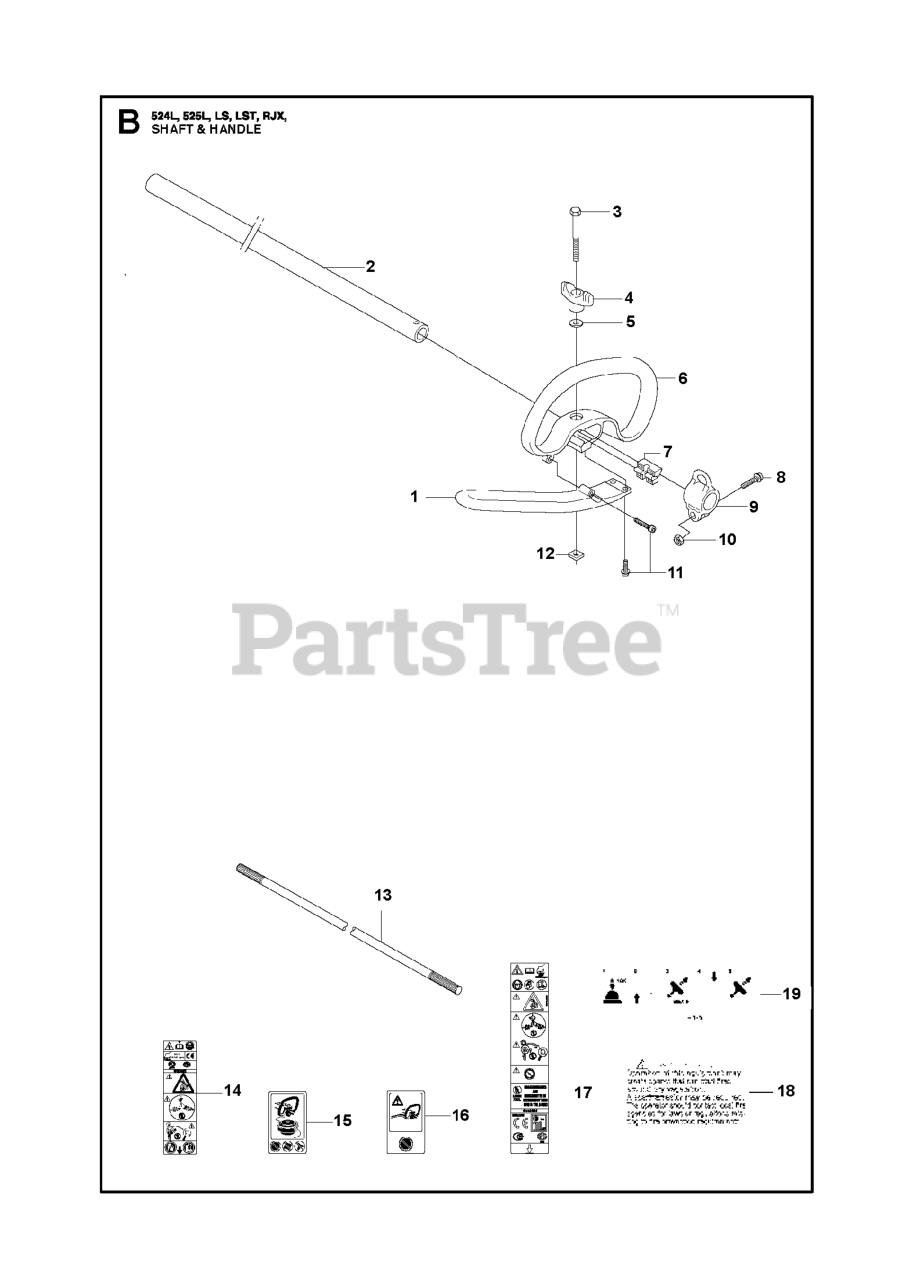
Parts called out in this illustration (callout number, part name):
1	HANDLE
2	TUBE
3	SCREW M6X50
3	BOLT
4	KNOB
5	WASHER
6	HANDLE
7	SPACER PLASTIC
8	SCREW
9	HARNESS HOLDER
10	NUT
11	SCREW IHSCFTO
13	DRIVESHAFT
14	LABEL WARNING 110DB/10000RPM
15	DECAL WARNING "NO BLADES"
16	DECAL
17	DECAL WARNING
18	DECAL SPARK ARRESTOR WARNING
19	DECAL START REMINDER 523/525
